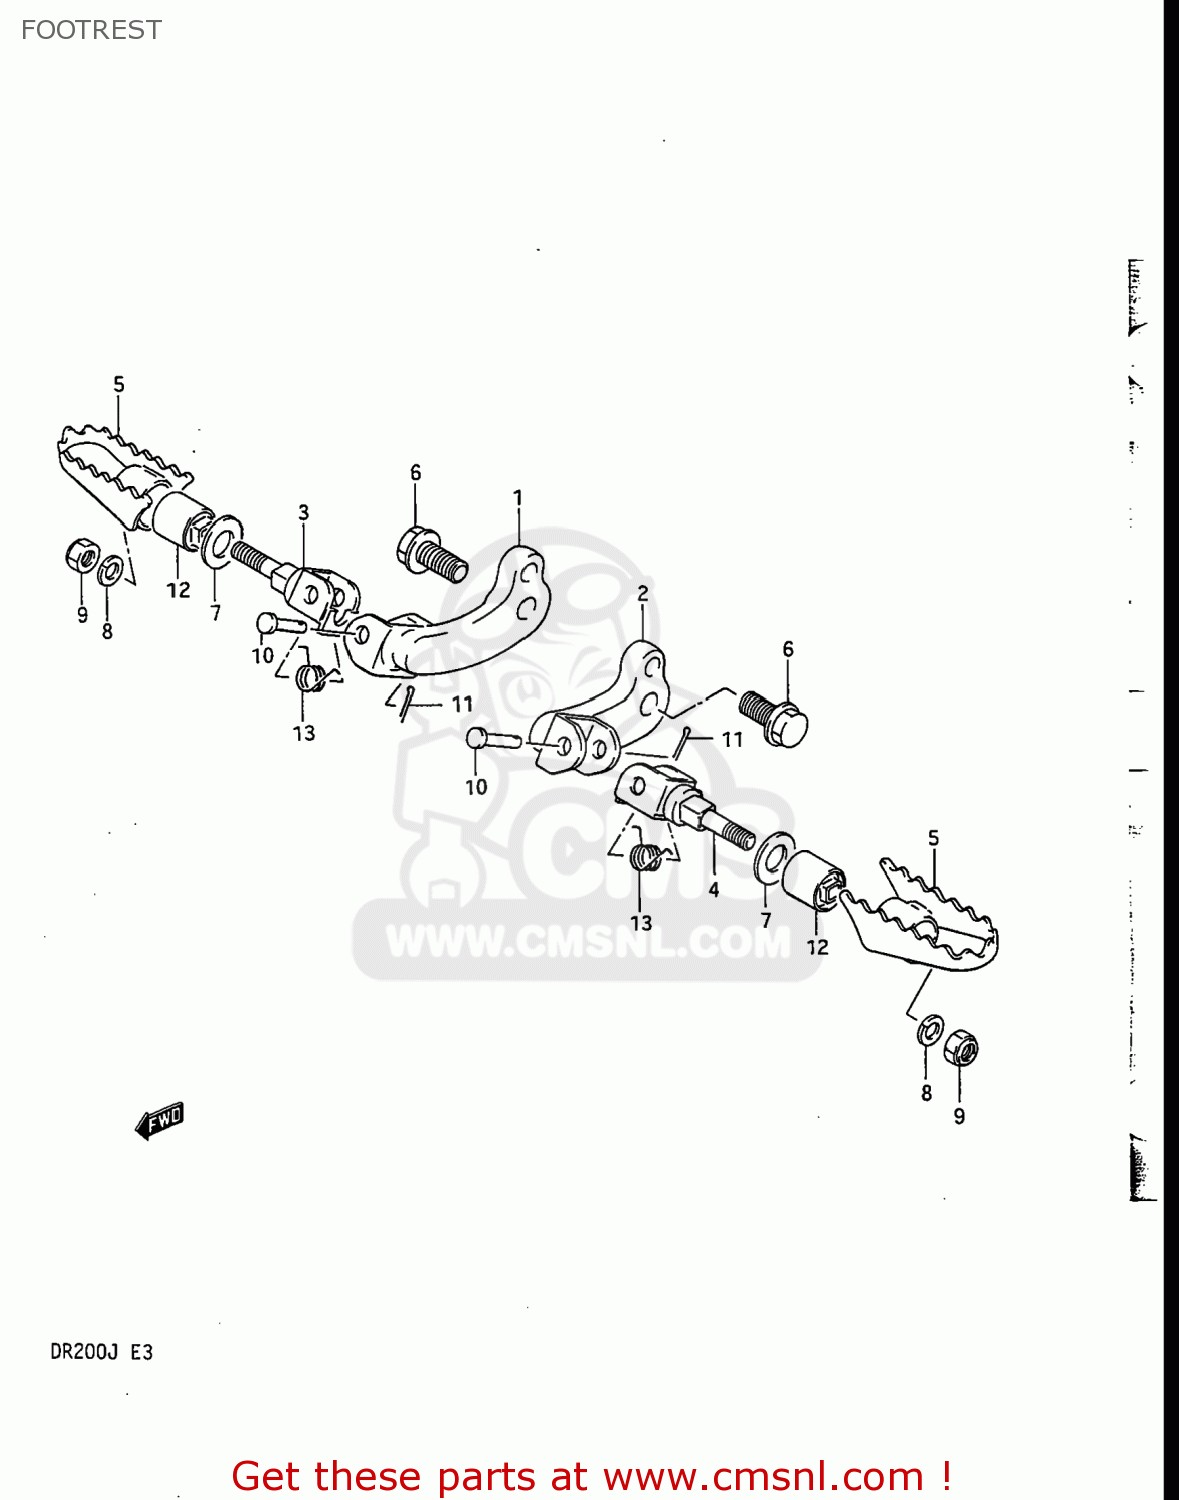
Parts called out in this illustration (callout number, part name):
1	BAR,FRONT FOOTREST
2	BAR,FRONT FOOTREST,LEFT
3	BRACKET,FRONT FOOTREST
4	HOLDER COMP,FRONT FOOT
5	FOOTREST,FRONT
6	BOLT
7	WASHER
8	WASHER,LOCK
9	NUT
10	PIN
11	PIN
12	BUSH
13	SPRING
